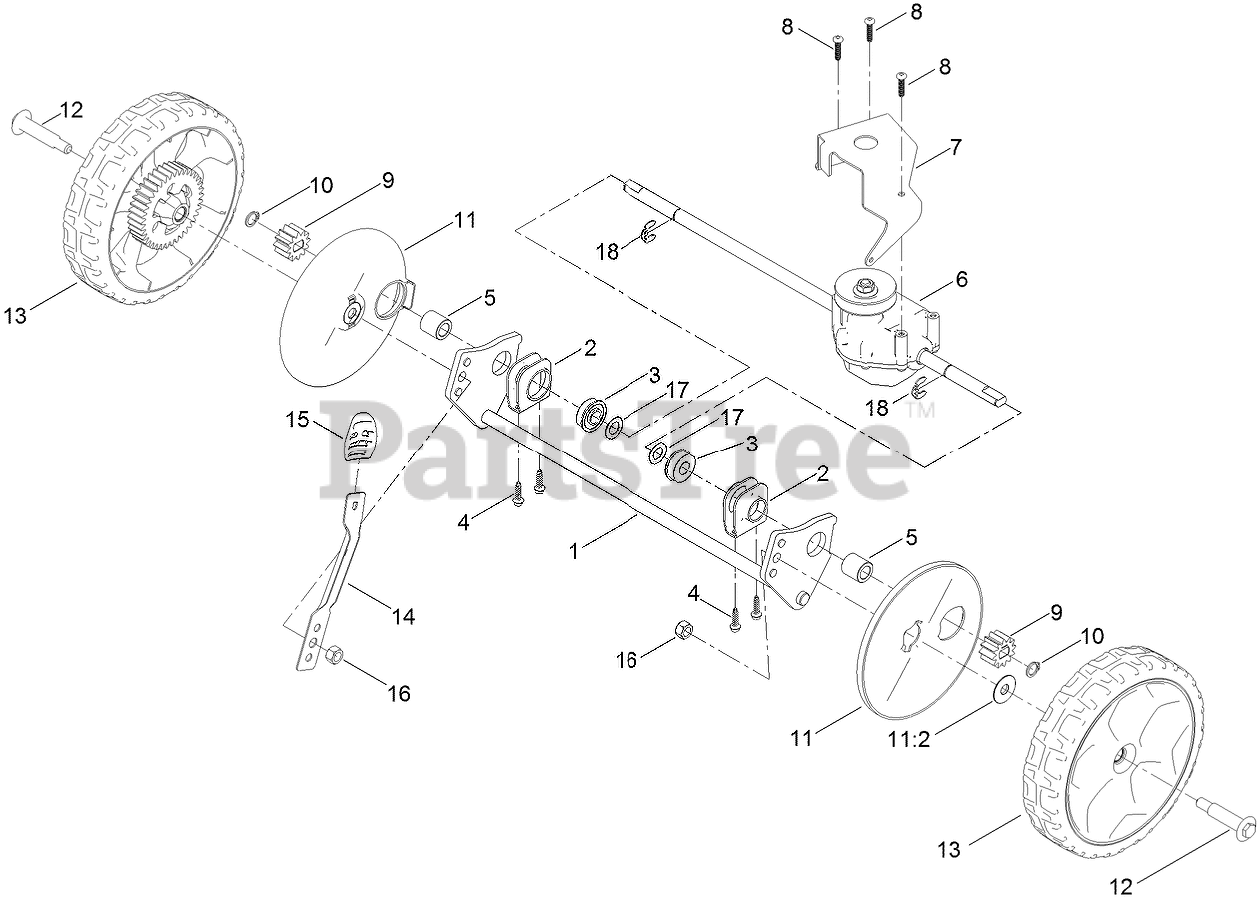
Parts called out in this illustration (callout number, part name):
1	AXLE-REAR
2	RETAINER-BEARING
3	BEARING-BALL
4	SCREW-HWH
5	BUSHING-SLEEVE
6	TRANSMISSION
7	BRACKET-TRANSMISSION
8	SCREW-PLASTITE
9	GEAR-PINION
10	RING-RETAINING
11	WHEEL COVER ASM
11:2	WASHER-STEPPED
12	BOLT-SHOULDER
13	8 INCH WHEEL GEAR ASM
14	ARM-SPRING
15	KNOB-LEVER, HOC
16	LOCKNUT
17	WASHER-PLAIN
18	RING-RETAINING,CLIP
